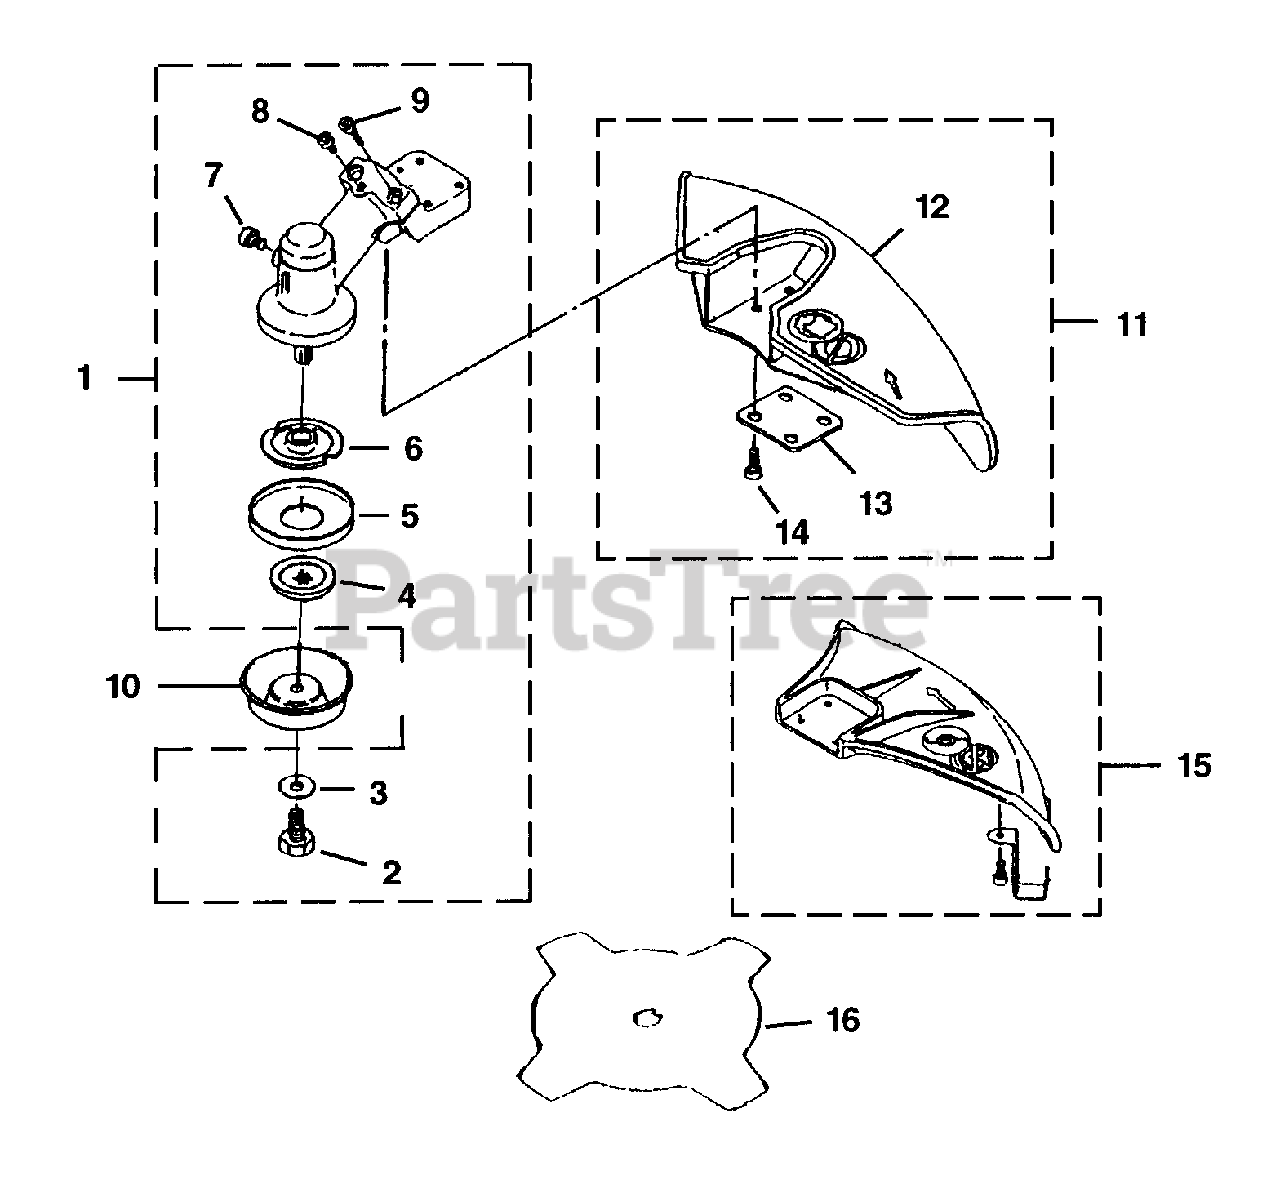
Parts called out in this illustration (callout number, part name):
1	GEAR CASE ASSY
2	BLADE BOLT M8, LH
4	BLADE CAP
5	GRASS COVER (B)
6	BLADE HOLDER
7	TORX BOLT M6 X 8
8	TORX BOLT M5 X 10
9	TORX SCREW M5 X 20
10	BOLT COVER
11	GUARD ASSEMBLY
14	TORX SCREW M5 X 20
15	GUARD COMPLETE
16	QUAD BLADE
